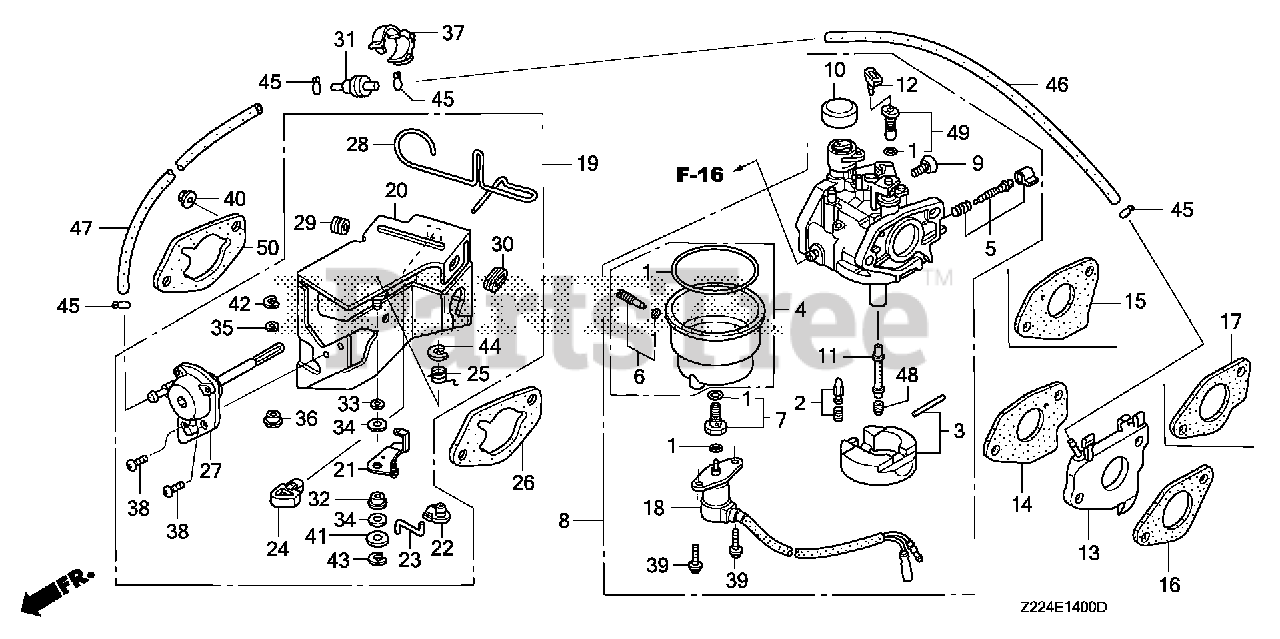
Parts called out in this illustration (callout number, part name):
1	GASKET SET
2	VALVE SET, FLOAT
3	FLOAT SET
4	CHAMBER SET, FLOAT
5	SCREW SET (Honda Code 4219879). (CARBURETOR NO.)
6	SCREW SET, DRAIN (ADVENTURE GREEN) (CARBURETOR NO.)
7	SCREW SET B
8	CARBURETOR ASSY. (BE72L A)
9	SCREW, THROTTLE STOP
10	CAP, CHOKE LEVER DUST
11	NOZZLE, MAIN
12	COLLAR, SET
13	INSULATOR, CARBURETOR
14	GASKET, CARBURETOR
16	GASKET, INSULATOR
18	VALVE ASSY., SOLENOID
19	STAY ASSY., MANUAL CHOKE
20	STAY, SOLENOID
21	LEVER, CHOKE
22	JOINT, ROD
23	ROD, CHOKE
24	STOPPER, CHOKE ROD
25	SPRING, MANUAL CHOKE
26	GASKET, AIR CLEANER
27	DIAPHRAGM ASSY.
28	ROD, CHOKE CONTROL
29	GROMMET, CHOKE ROD
30	GUIDE, CHOKE ROD
31	VALVE, DASHPOT CHECK
32	BUSH, ARM PIVOT
33	WASHER, CHOKE LEVER
34	SEAL, CHOKE LEVER
35	WASHER, THRUST (2.7X8)
36	COLLAR, LEVER
37	CLIP, WIRE HARNESS
38	SCREW, PAN (5X12)
39	SCREW-WASHER (5X12)
40	NUT, FLANGE (6MM)
41	WASHER, PLAIN (5MM)
42	E-RING (2MM)
43	E-RING (4MM)
44	E-RING (7MM)
45	CLIP, TUBE (B7)
46	BULK HOSE, VACUUM (3.5X8000) (3.5X130)
47	BULK HOSE, VACUUM (3.5X8000) (3.5X130)
48	JET, MAIN (#75) (CARBURETOR NO.)
48	JET, MAIN (#78) (CARBURETOR NO.)
48	JET, MAIN (#80)
49	JET SET, PILOT (#45)
50	SPACER, CARBURETOR
50	GASKET, AIR CLEANER
